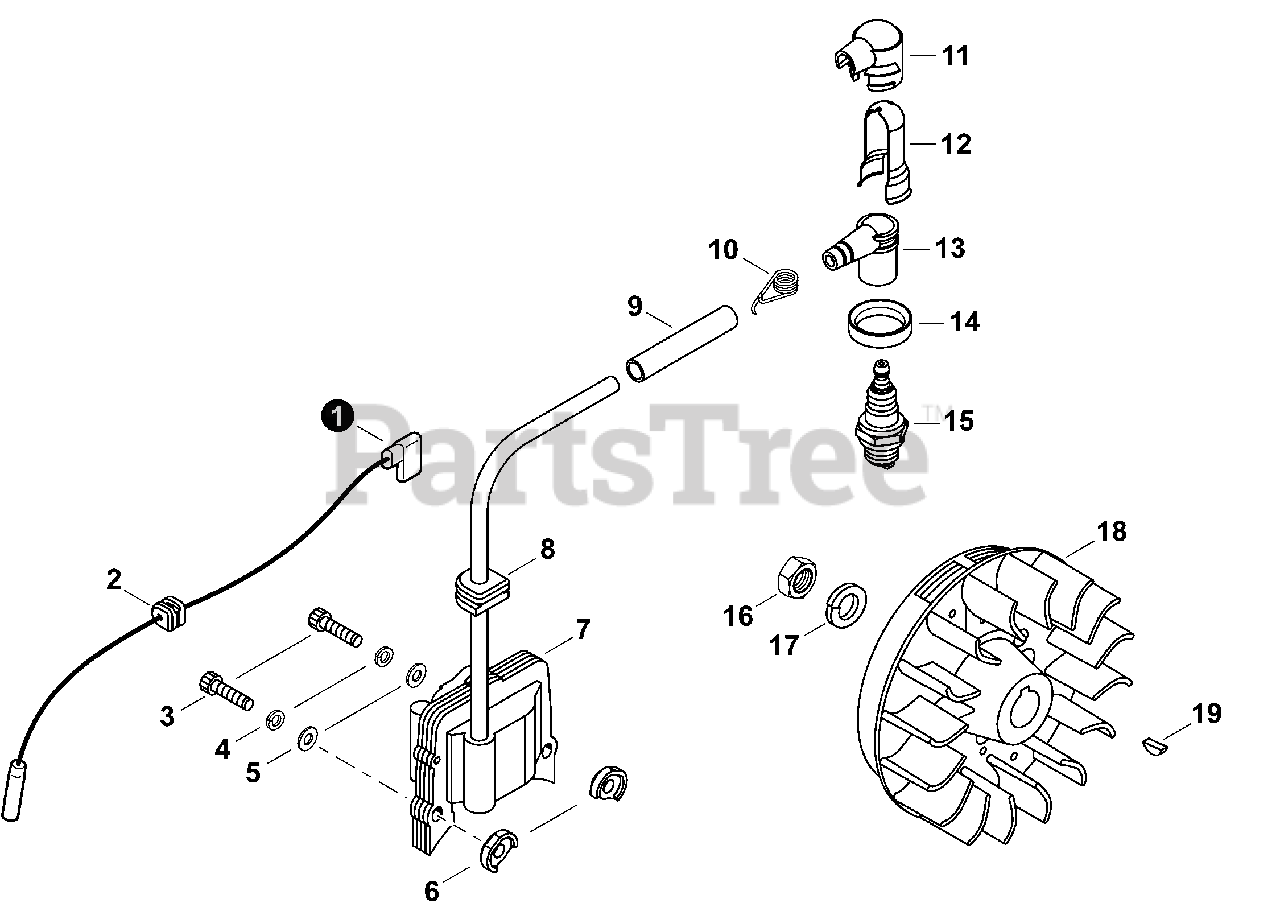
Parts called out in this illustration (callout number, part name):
1	LEAD - IGNITION
2	GROMMET, LEAD
3	BOLT M4x24
4	WASHER, SPRING 4
5	WASHER 4.3x9.6x0.8
6	COLLAR 4
7	COIL, IGNITION
8	GROMMET
9	TUBE, INSULATOR
10	TERMINAL, SPARK PLUG
11	COVER, CAP
12	SHIELD, SPARK PLUG
13	CAP, SPARK PLUG
14	SEAL, SPARK PLUG
15	SPARK PLUG - BMR6A
16	NUT 10x1.25
17	SCREW
18	FLYWHEEL
19	KEY, WOODRUFF 3x10
